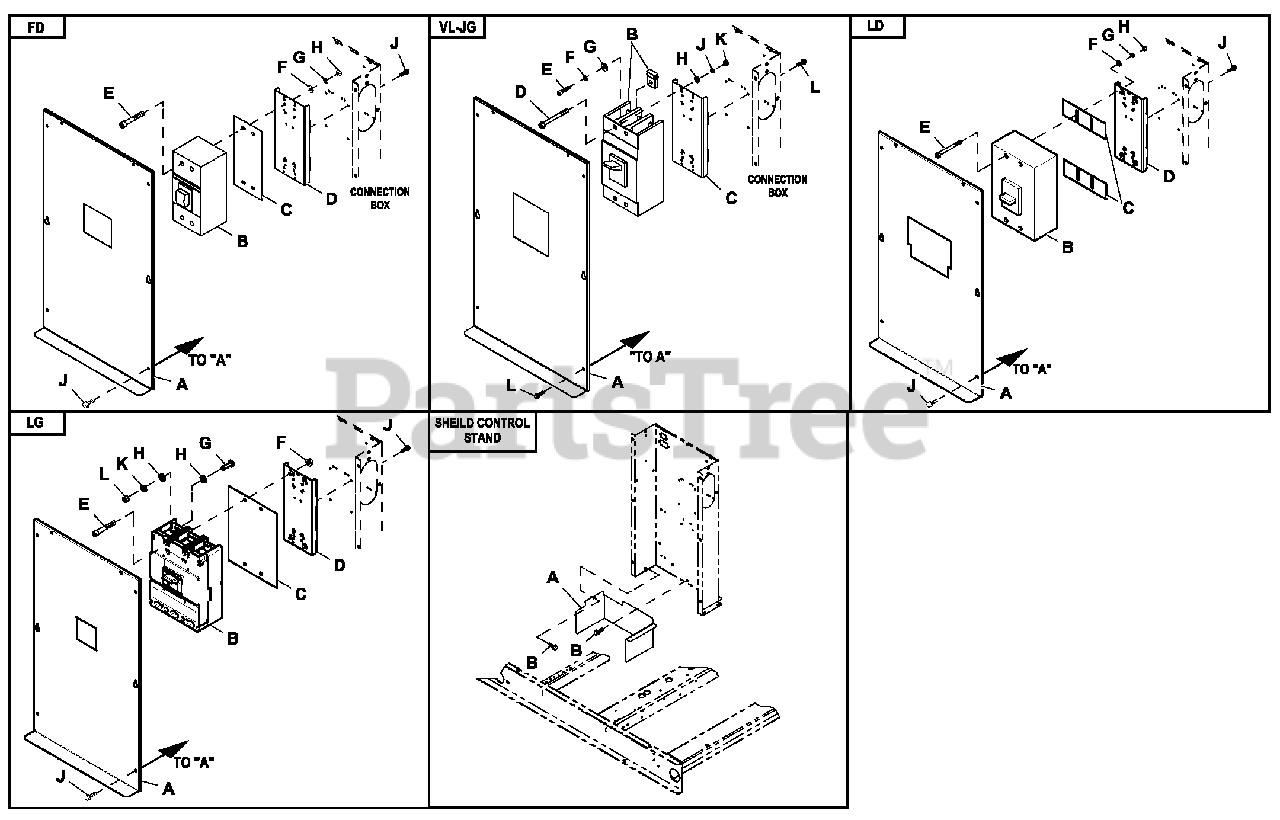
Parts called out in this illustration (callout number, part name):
A	COVER CB 3P S F D6 C5
B	CB 0150A3P 600V S FD6 LL
C	INSULATOR CB FD F RAME 30MIL
D	STANDO F F CB MOUNT CONBOX
E	SCREW SHC 1 /4-20X4.5 G8.8 NZ
F	WASHER FLAT 1/4-M6 ZINC
G	WASHER LOCK M6-1/4
H	NUT HEX 1/4-20 STEEL
J	SCREW HWHT M6-1 X 16 N WA Z/JS
A	COVER CB 3P S VL C5
B	CB 0300A 3P 600V S JG-VL LL
C	STANDO F F CB MOUNT CONBOX
D	SCREW RHM 1 0 -3 2X 4
E	SCREW SHC M8-1.25 X 20 C12.9
F	WASHER LOCK M8-5/16
G	WASHER FLAT 5/16-M8 ZINC
H	WASHER FLAT #10 ZINC
J	WASHER LOCK #10
K	NUT HEX #10-32 STEEL
L	SCREW HWHT M6-1 X 16 N WA Z/JS
A	COVER CB 2P S LD6 C5
B	CB 0500A 3P 600V S LD6
C	INSUL CIRCUIT BREAKER JD/LD
D	STANDOFF CB MOUNT CONBOX
E	SCREW RHM 1 /4 -2 0X 3
A	COVER CB 2P E LG C5
B	CB 0500A 3P 600V E LG LL
C	INSULATOR C B E 3 P LG
E	SCREW SHC M6-1.0 X 50 C8.8
F	NUT FLANGE M6-1.0 NYLOK
G	SCREW HHC M8-1.25 X 25 C8.8
H	WASHER FLAT 5/16-M8 ZINC
K	WASHER LOCK M8-5/16
L	NUT HEX M8-1.25 G8 CLEAR ZINC
A	SHIELD WIRING CHUTE 150KW
B	SCREW HWHT M6-1 X 16 N WA Z/JS
